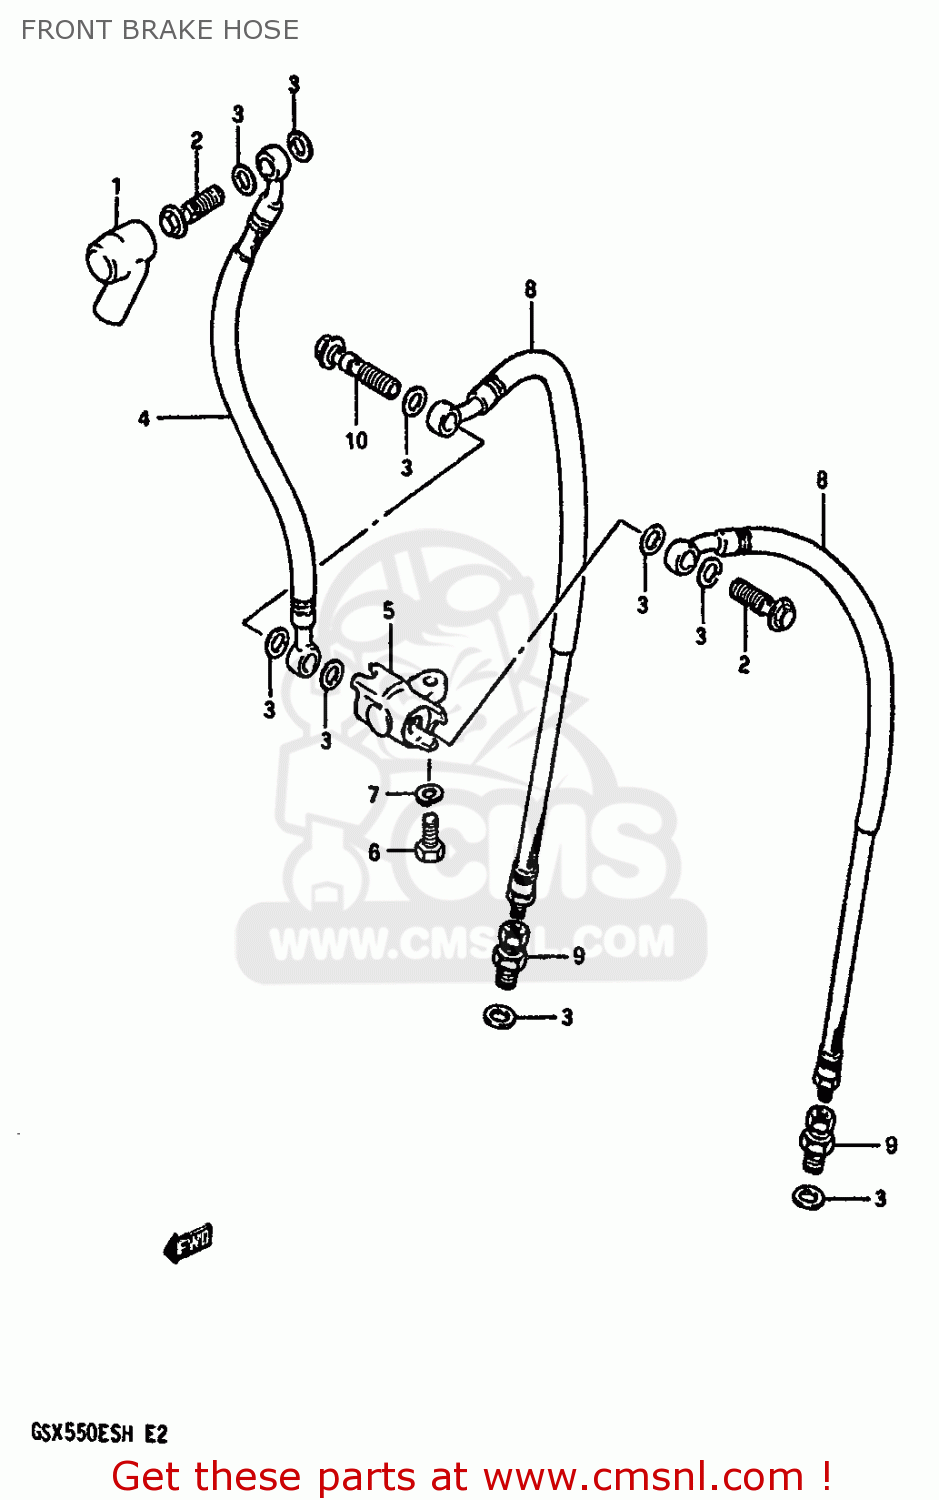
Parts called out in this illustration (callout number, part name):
1	BOOT,MASTER CYLINDER
2	BOLT UNION
3	WASHER(10X15X1.5)
4	HOSE,FRONT BRAKE
5	JOINT,BRAKE HOSE
6	BOLT
7	WASHER,LOCK
8	HOSE,BRAKE NO.2
9	ADAPTER,BRAKE HOSE
10	BOLT UNION
